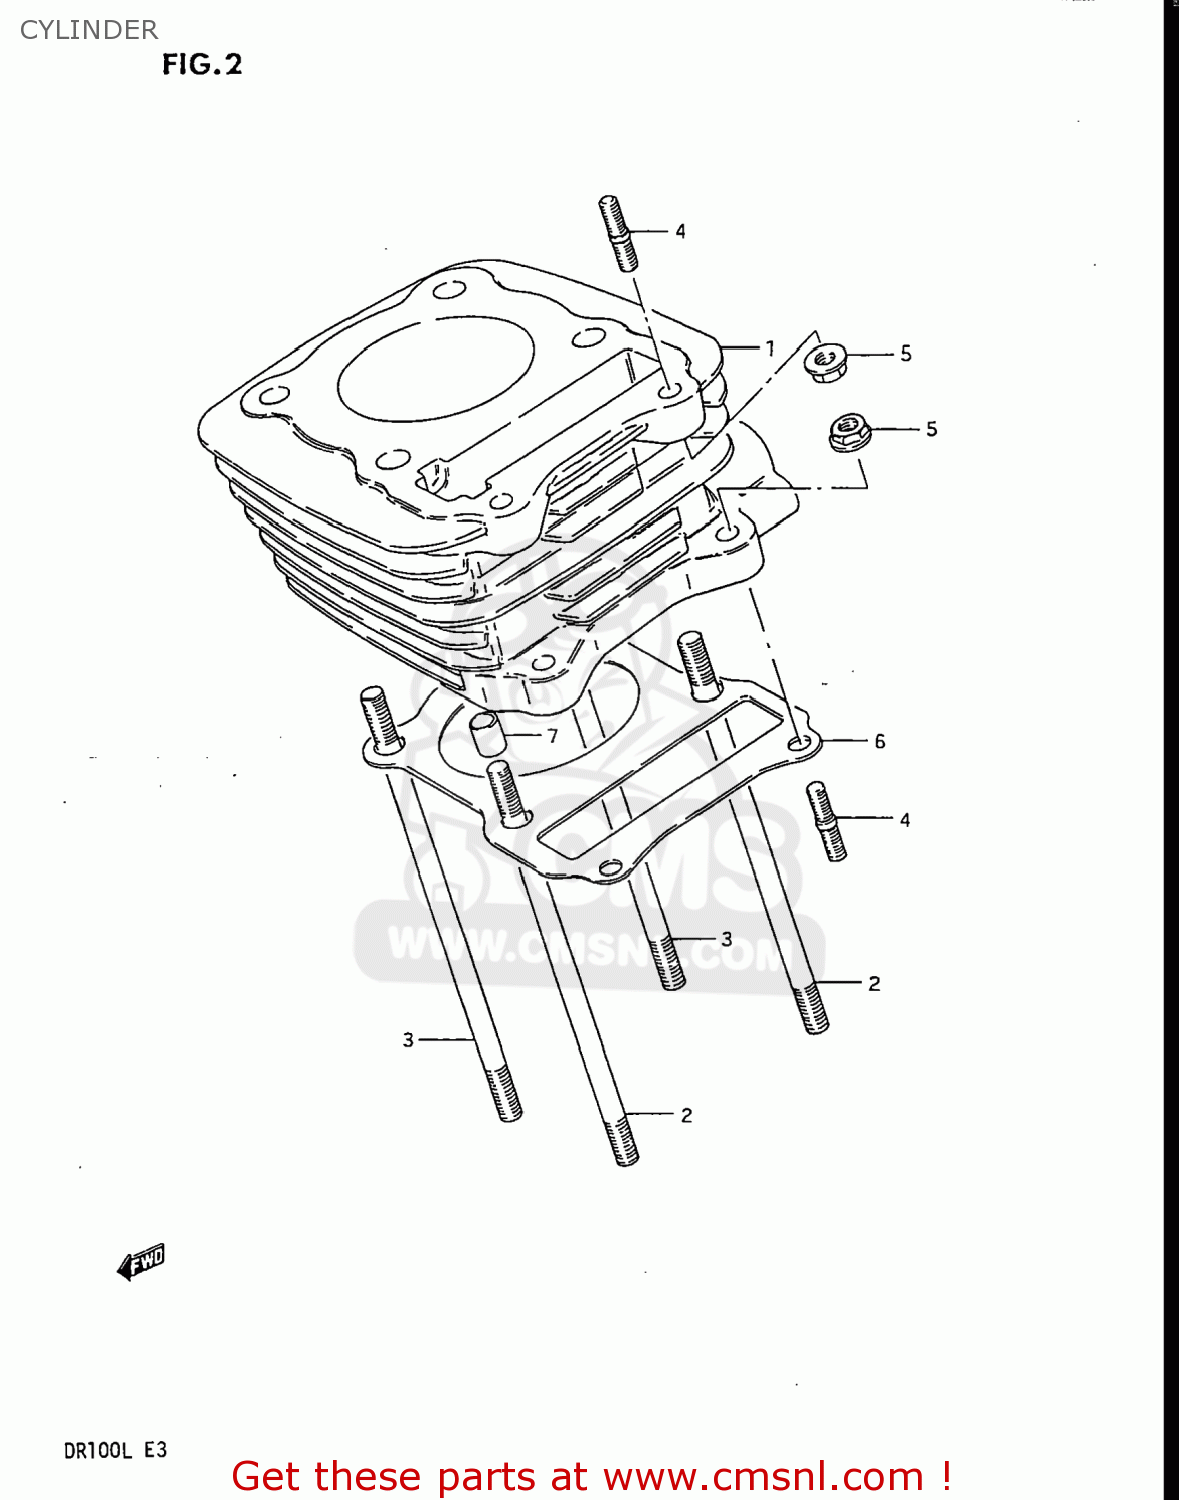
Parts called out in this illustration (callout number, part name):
1	CYLINDER
2	BOLT,STUD
3	BOLT,STUD
4	STUD 6X25
5	NUT 6MM
6	GASKET,CYLINDER (MCA)
7	PIN
